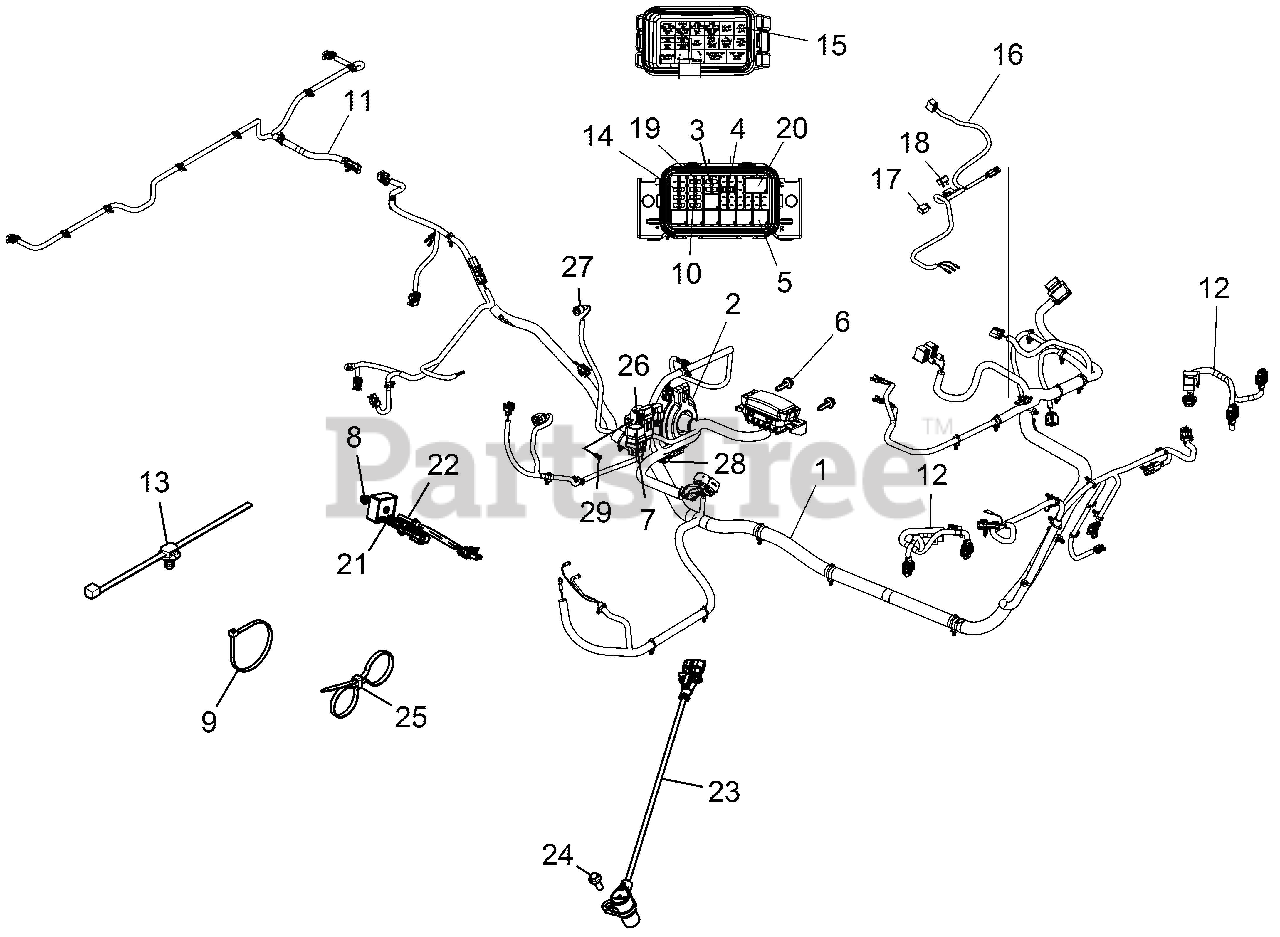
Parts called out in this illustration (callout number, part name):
1	HARNESS-CHASSIS,DSL,EPS
1	KIT, FUSIBLE LINK, 2MM
1	KIT, FUSIBLE LINK, 1MM
1	KIT, FUSIBLE LINK, .8MM
2	GROMMET-CHASSIS HARNESS
3	FUSE-5A,MINI BLADE
4	BREAKER-CIRCUIT,20 AMP
5	RELAY-SPST,SERIES 303,SEALED
6	SCR-M6X1.0X20,HXHD,FLG,TDFM,BL
7	COVER-DIAGNOSTIC,W/CLIP
8	NUT-M6X1.0,FLG-NYLOC-OLIVE D
9	CABLE TIE (10)
10	FUSE,PARK,20 AMP,(10)
11	HARNESS-BOX-ARIENS SPLY
12	HARNESS-HEADLIGHT,ARIENS
13	CLIP-ROUTING
14	FUSE,MAIN,30 AMP,(10)
15	DECAL, FUSE BLOCK
16	HARNESS-BOX,LIFT
17	RELAY-MICRO,SPST,35A,SEALED
18	BREAKER-CIRCUIT,20 AMP,SEALED
19	FUSE, MINI BLADE, 15 AMP
20	RELAY-SPDT,SERIES 301,SEALED
21	RELAY, SOLID STATE,9A,LONG LD
22	BOLT-M6X1.0X35,HXFLG/SH-OLV D
23	SENSOR-CRANK POSITION
25	CABLE TIE
26	CLIP, X-MAS-TREE
27	BOOT, OIL PRESSURE SWITCH
28	TVS, 30VOLT
29	CLIP, PLASTIC DART, NYLON
